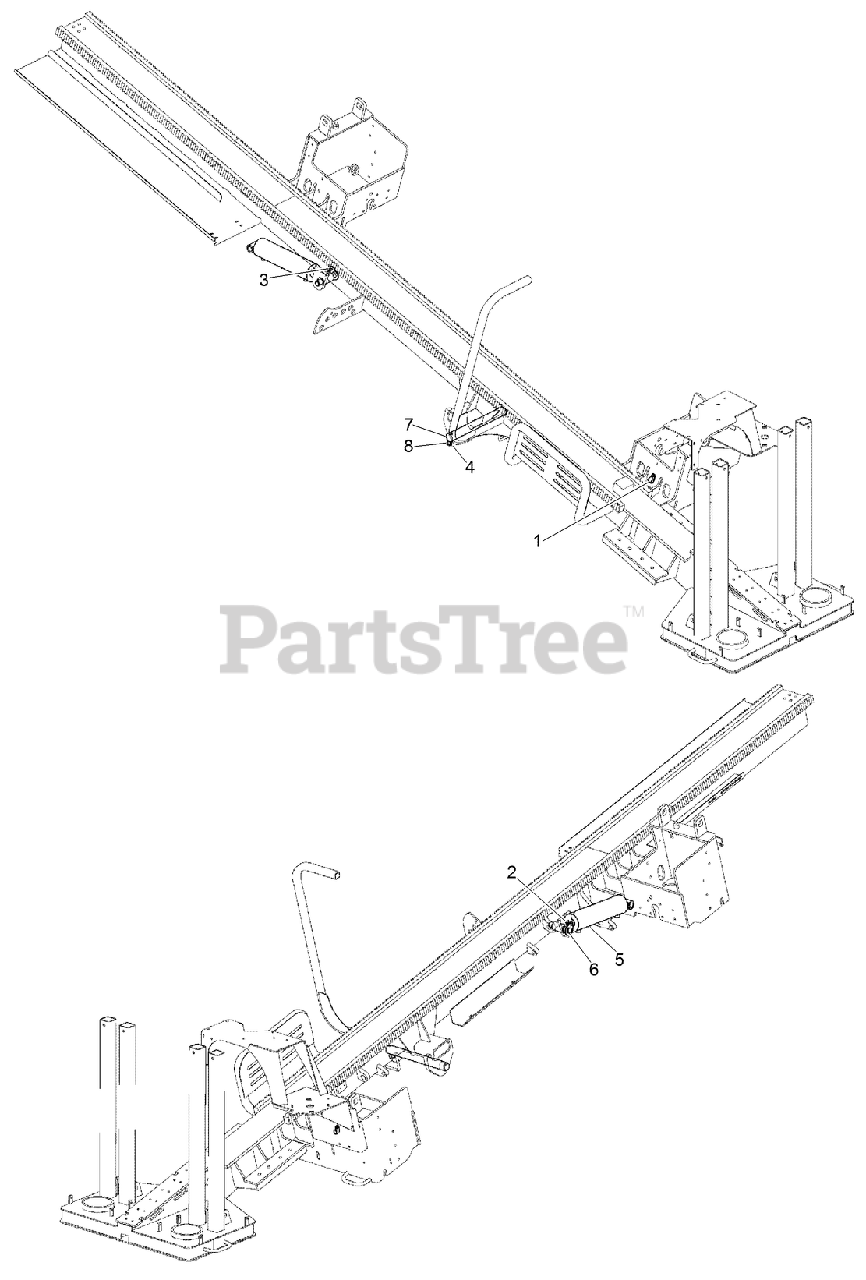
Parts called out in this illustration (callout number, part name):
1	CLAMP - Insul 25.4mm M12 Bolt ZND
2	SCREW, METRIC FLANGE w/BODY - M8 x 40
3	NUT-TORQUE, PREVAILING
4	SCREW-HH
5	HYD CYLINDER ASM
6	PIN-PIVOT
7	PIN-PIVOT, MAIN
8	PIN-RETAINER
